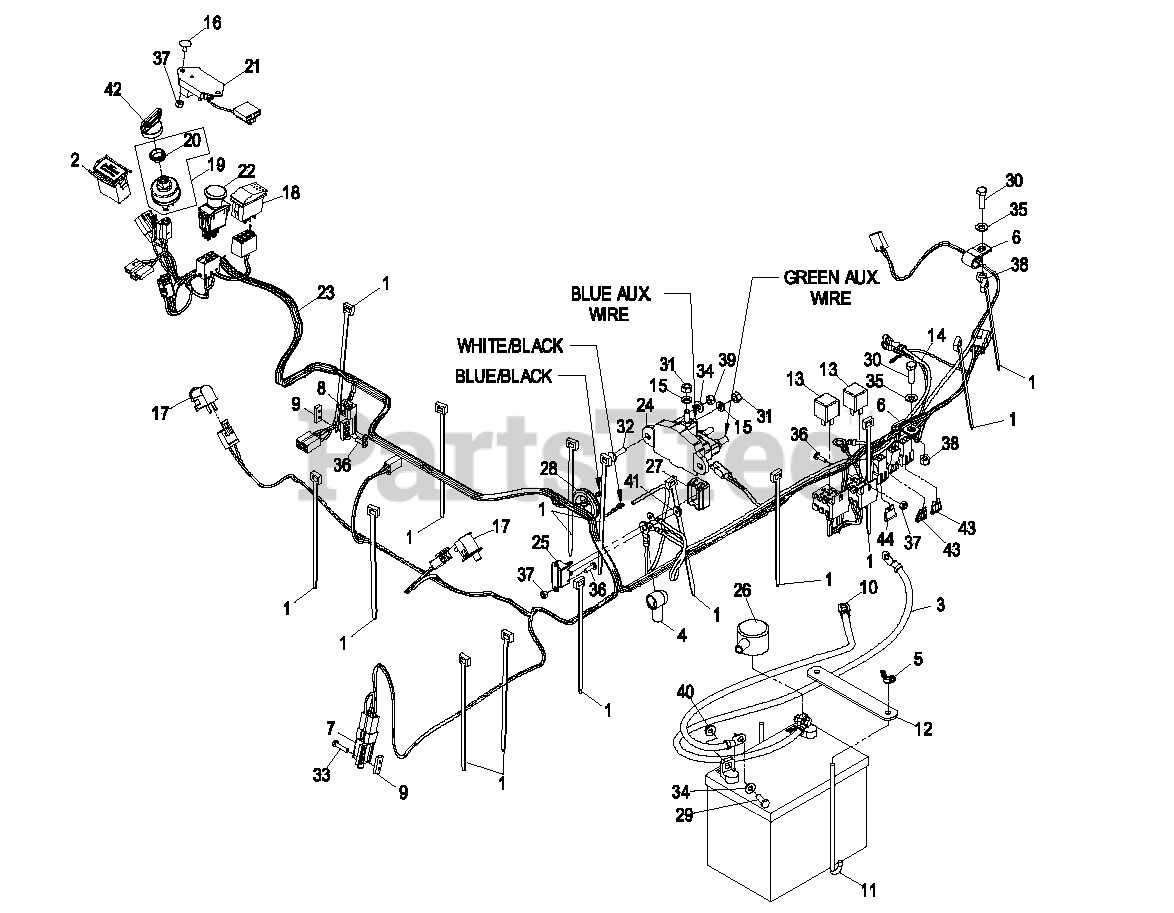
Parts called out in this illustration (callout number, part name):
1	TIE-PLASTIC
2	METER-HOUR
4	INSULATOR-SOLENOID
5	WINGNUT
6	CLIP-LOOM
7	SWITCH-BRAKE
9	PLATE-TAPPED
10	WIRE-GROUND
11	BOLT-HOLDDOWN
12	STRAP-HOLDDOWN, BATTERY
14	HARNESS,AUX HYDRAULICS
15	WASHER-LOCK
16	BOLT-CARR
17	SWITCH-BAIL
18	SWITCH,ROCKER (ON)-NONE-(
19	ASM,SWITCH W/NUT
20	NUT-SWITCH, IGNITION
21	MODULE-DELAY, SEAT
22	SWITCH-PTO
23	HARNESS,WIRING FMZ KOHLER
23	HARNESS,FMZ BV
24	CONTACTOR, REVERSING POLA
25	CIRCUIT BREAKER,40A
26	INSULATOR-BATTERY
27	COVER,CIRCUIT BREAKER
28	GROMMET-RUBBER
29	SCREW-HH
30	SCREW-HH
31	NUT-HEX
32	Bolt, Carriage 1/4-20 X 1
33	SCREW-PPH
34	WASHER-FLAT
35	WASHER-PLAIN
36	SCREW-PPH
37	NUT-LOCK, NI
38	NUT-LOCK, NI
39	NUT-LOCK, NI
41	NUT-KEPS
42	KEY-IGNITION
43	FUSE-BLADE TYPE, 20 AMP
44	FUSE-BLADE, 15 AMP
45	FUSE-BLADE TYPE, 30 AMP
